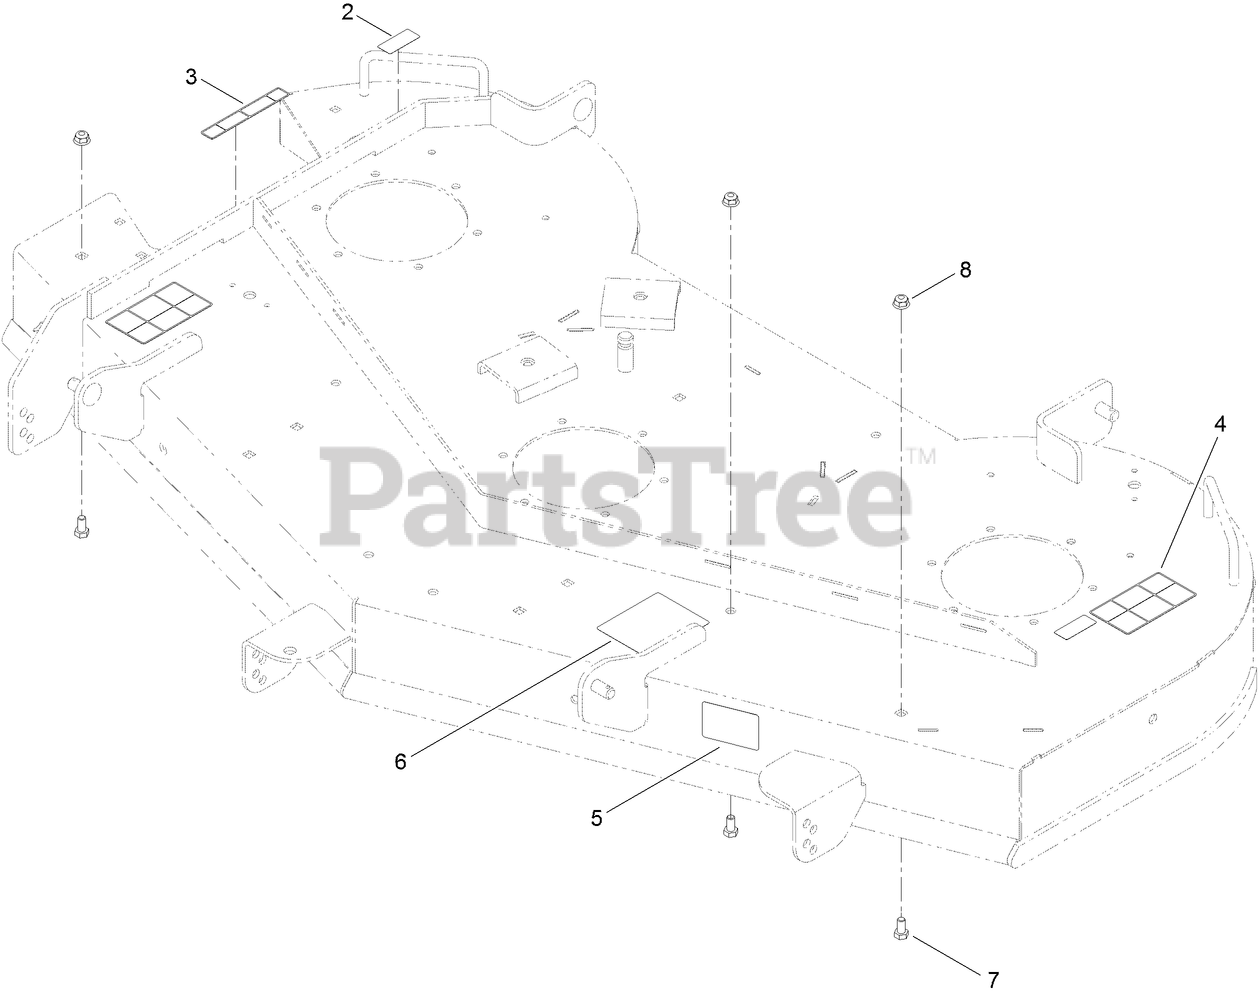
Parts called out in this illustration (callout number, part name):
2	DECAL-DANGER
3	DECAL-DANGER
4	DECAL-DANGER
5	DECAL-SCALP, ANTI
6	DECAL-ROUTING, BELT
7	SCREW-HH
8	NUT-HF, NI
